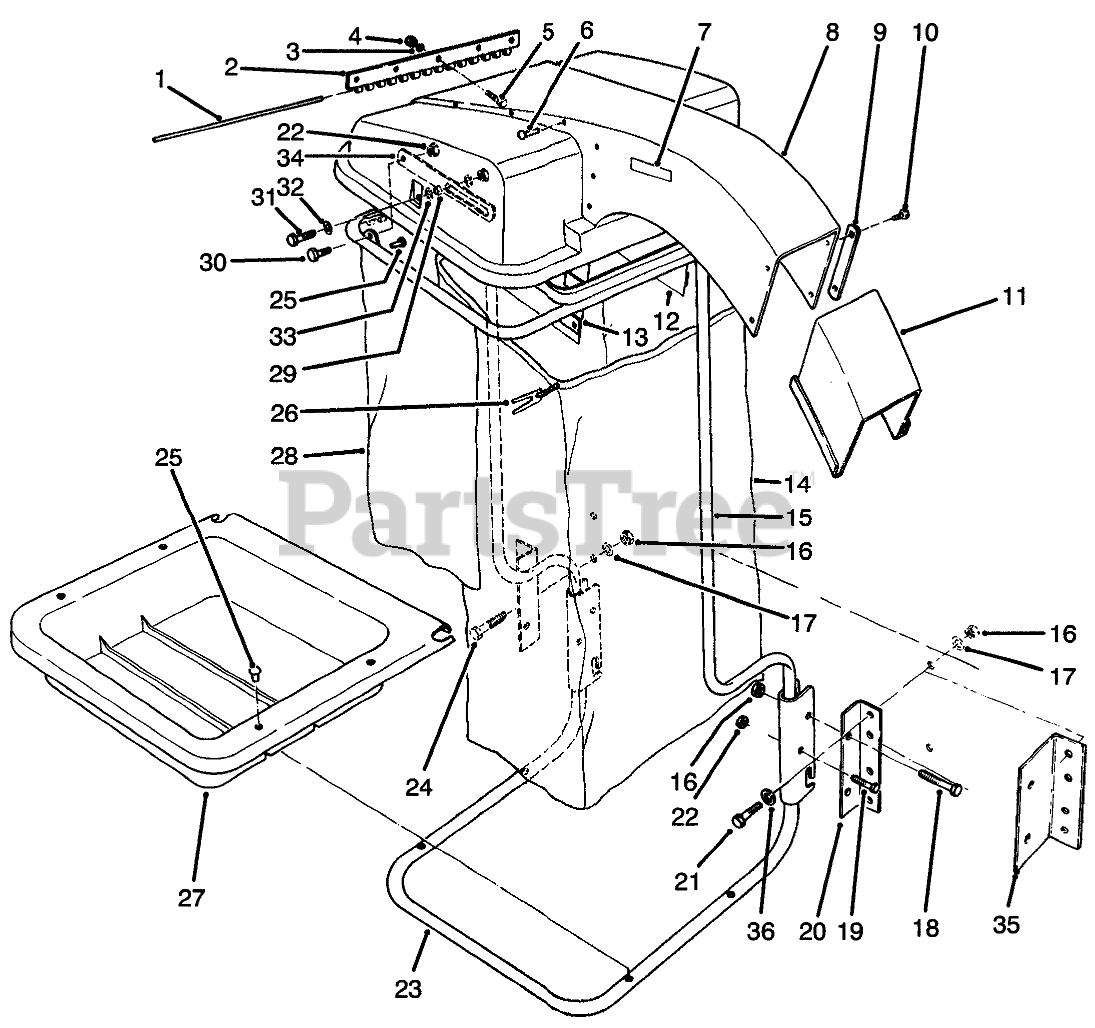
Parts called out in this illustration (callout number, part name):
1	HOOD HINGE PIN
2	Hinge Half
3	WASHER-FLAT
4	NUT-LOCK, NI
6	RIVET-BLIND
7	Decal-Caution
8	Hood Assembly (Incl. Ref. #7)
9	PLATE-NUT B
10	SCREW-HSBH
11	Extension-Snout
12	Screen Left Hand
13	Screen Right Hand
14	BAG-CLOTH, 32"
15	Upper Support Tube Assy. (Incl. Ref. #25 & 28)
16	NUT-LOCK, CONE
17	WASHER-FLAT
18	SCREW-HH
19	SCREW-HH
20	BRKT-FRAME B
21	SCREW-HH
22	NUT-LOCK, CONE
23	Lower Support Tube Assy. (Incl. Ref. #25 & 27)
24	SCREW-HH
26	BAG CORD FASTENER
27	Tray-Lower
28	Skirt-Bagging Frame
29	SPACER - PIVOT ARM
30	SCREW-HH
31	SCREW-HH
32	WASHER-PLAIN
33	WASHER-FLAT
34	Stop-Hood
35	Bracket-Frame (Use with 62" Blower Kit
36	WASHER-LOCK
